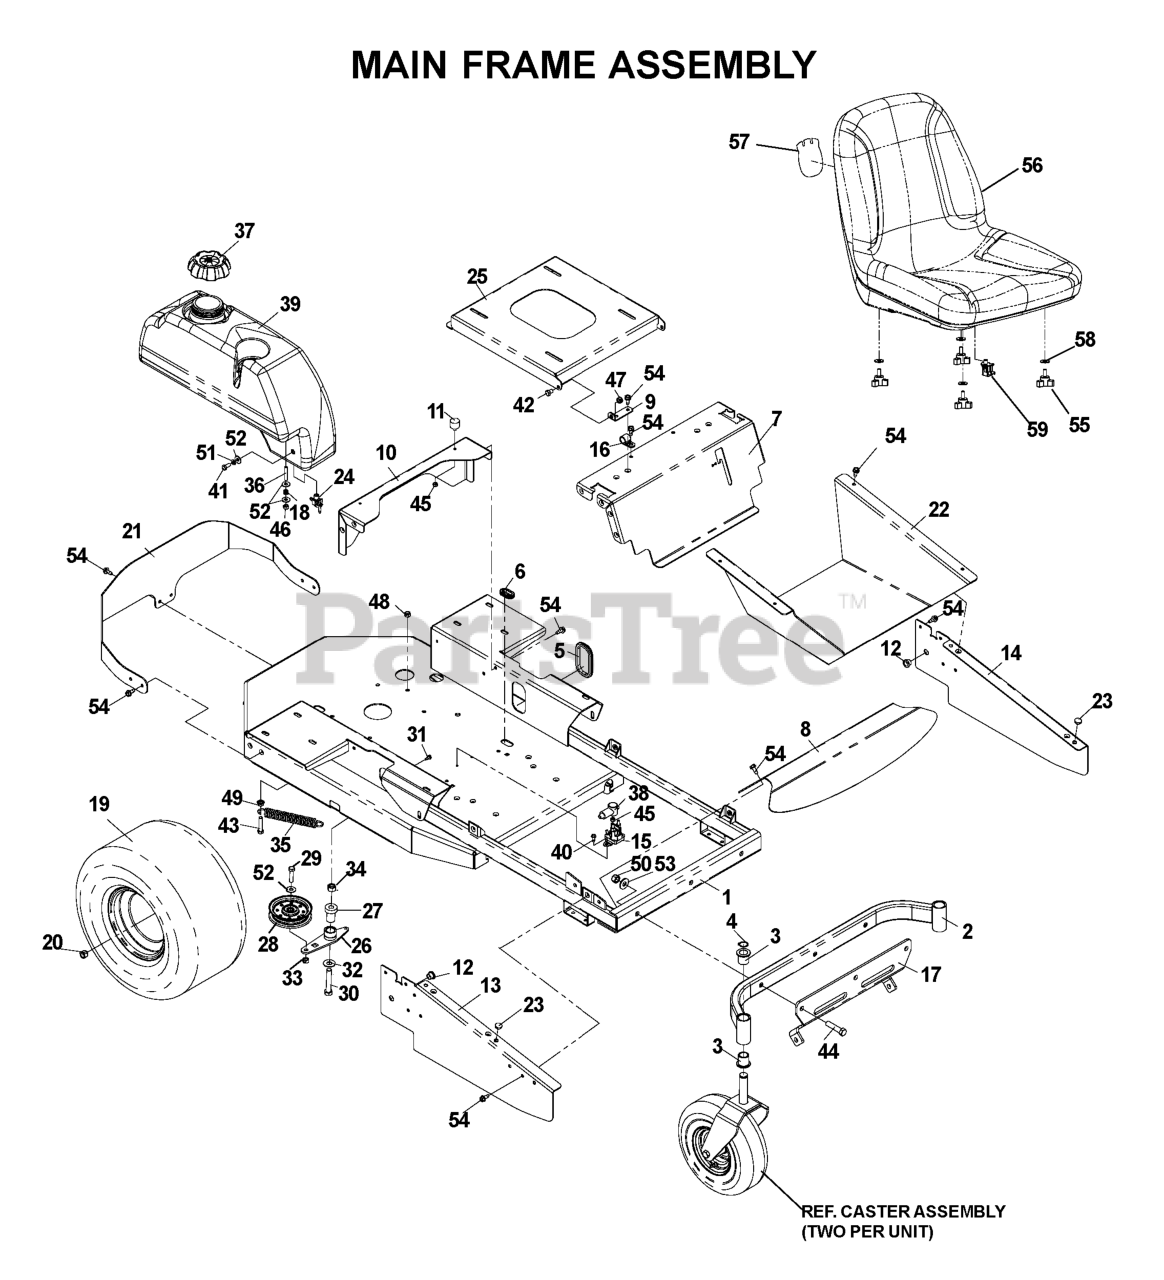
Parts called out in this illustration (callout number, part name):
1	MAINFRAME W/DECALS
2	CASTER AXLE W/BUSHING
3	BUSHING, FLANGED
4	RETAINING RING, 7/8"
6	RUBBER GROMMET
7	SEAT SUPPORT W/DECALS
8	FRONT FOOT PLATE
9	SEAT BRACKET-BLACK
10	REAR SUPPORT-ORANGE
11	STUD/PLATE MOUNT
12	BUSHING, FLANGED NYLON
13	RH FRAME SIDE-ORANGE
14	LH FRAME SIDE-ORANGE
17	STRUT MOUNT
19	TIRE ASSY
20	LUG NUT 1/2F
21	REAR BUMPER-BLACK
22	FLOOR PAN-ORANGE
23	GROMMET, BUMPER
24	FUEL VALVE
25	SEAT SUPPORT W/DECALS
26	PUMP IDLER ARM WELDMENT
27	IDLER SPINDLE
28	FLAT IDLER PULLEY
29	HCS 3/8C X 1 1/2
30	HCS 1/2C X 2 3/4
31	SCREW #10 X 1/2 SELF TAPPING
32	WASHER 1/2 FLAT
33	NUT 3/8C CENTERBLOCK
34	NUT 1/2-13 HEX NYLOC ZD
36	STUD, 5/16C
37	FUEL CAP ANTI-SPLASH
39	LEFT TANK W/CUP HOLDER
40	SCREW 1/4 X 5/8
41	HCS 5/16C X 3/4
42	BOLT .375 X .5
43	HCS 3/8C X 2 1/4
44	HEX SCREW-.5C X 2.25
45	NUT.1/4-20.HEX.NYLOC.ZD
46	NUT 5/16 NYLOC
47	NUT 3/8C CENTERBLOCK
48	NUT 3/8-16 NYLOC
49	NUT 3/8C WHIZ
50	NUT 1/2-13 HEX NYLOC ZD
51	WASHER.LOCK.HVY.HLCL.SPR.5/16
52	WASHER 5/16 FLAT
53	WASHER 1/2 FLAT
54	BOLT 5/16-18 X 3/4
55	KNOB W/STUD
57	DECAL, CROWN H
58	WASHER 5/16 FLAT
59	SEAT SWITCH
539108008	RIM.8"X6.38".ZTR
539108009	TIRE 18 X 9.5-8 4 PLY
539912234	VALVE STEM TR-412
